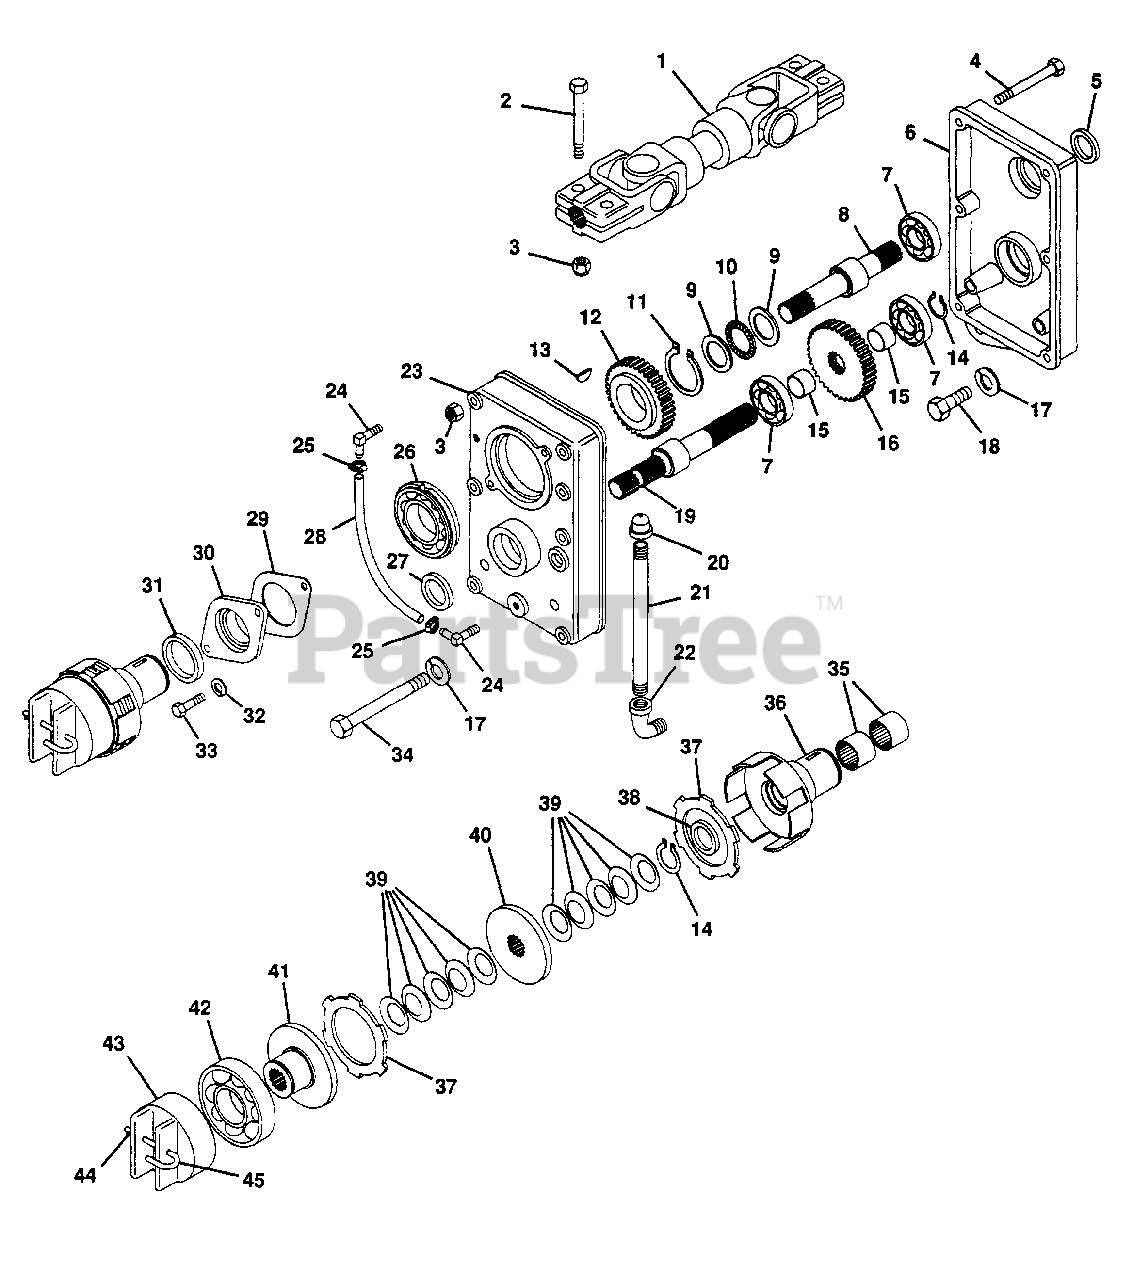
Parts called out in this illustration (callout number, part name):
1	Assembly, PTO U-Joint
2	Bolt, Hex 3/8-16x1.75
3	Nut, Lock 3/8-16
4	Bolt, Hex 3/8-16x3.50
5	Seal, Oil .984x1.596x.250
6	Case, PTO
7	Bearing, Ball .984x2.047x.591
8	Shaft, PTO Input(Upper)
9	Bearing, Thrust Race
10	Bearing, Needle Thrust
11	Ring, Retaining 1.969 Shaft
12	Gear, PTO Input 10 Dp 43T
13	Key, Woodruff .25x1.00 Hrd #15
14	Ring, Retaining
15	Bush., St. 1.01x1.25x.645 Stl.
16	Gear, PTO Output 10 Dp 43T
17	Washer, Lock 1/2 Reg.
18	Bolt, Hex 1/2-13x1.50
19	Shaft, PTO Output(Lower)
20	Cap, Pipe 3/8 NPT
21	Nipple, Pipe 3/8x6
22	Elbow, 3/8 90 Degree Street
23	Cover
24	Elbow, Hose
25	Clamp, Hose
26	Bearing, Ball 1.968x3.149x.63
27	Seal, Oil 1.250x1.752x.250
28	Hose, 1/4 In. Vinyl
29	Gasket, Front PTO Cap
30	Cap, Front PTO
31	Seal, Oil 2.250x3.005x.375
32	Washer, Lock 5/16 Reg.
33	Bolt, Hex 5/16-18x.75
34	Bolt, Hex 1/2-13x4.25
35	Bearing, Roller
36	Hub, PTO Clutch
37	Disc, Clutch
38	Seal, Oil 1.000x1.500x.250
39	Spring, Belleville
40	Plate, Clutch
41	Hub, Clutch Actuating
42	Bearing, Ball 1.574x3.149x.70
43	Trunion, Fwd/Rev Clutch
44	Pin, Cotter .063x.75
45	Pin, Clutch Spring
